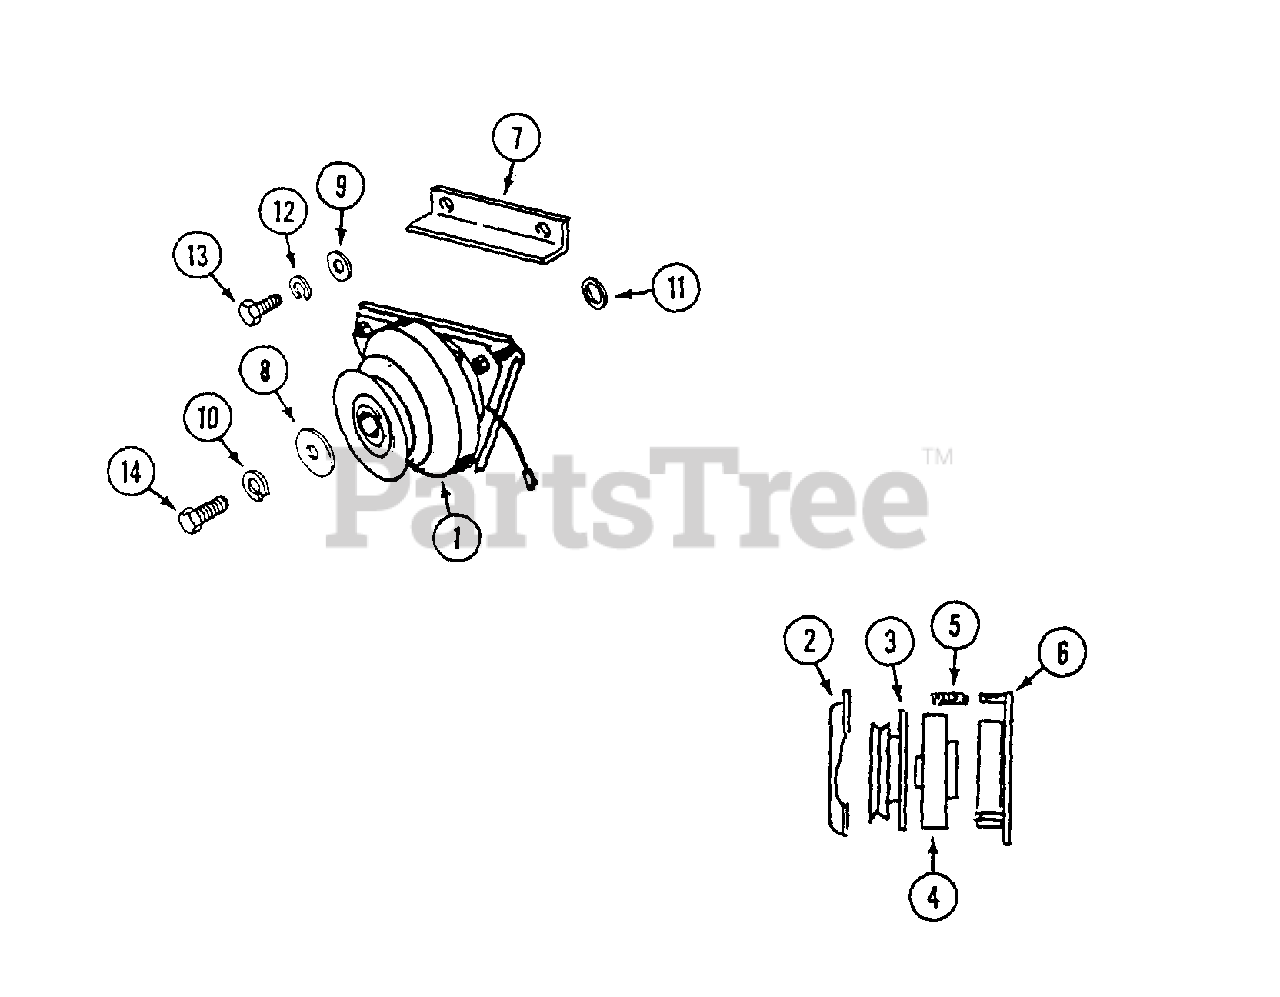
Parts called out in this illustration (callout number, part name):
1	CLUTCH ASSEMBLY
2	BRAKE - clutch
3	ARMATURE - clutch
4	ROTOR - clutch
5	KIT - spring and nut (3 each)
6	COIL - clutch
7	BRACKET - clutch stop
8	WASHER - retaining
9	WASHER - 7/16"
10	LOCKWASHER - 3/8"
11	WASHER - 1-1/8" spacer
12	LOCKWASHER - 7/16"
13	BOLT - 7/16" - 14 x 1-1/4"
14	BOLT - 3/8" - 24 x 1-1/2"
